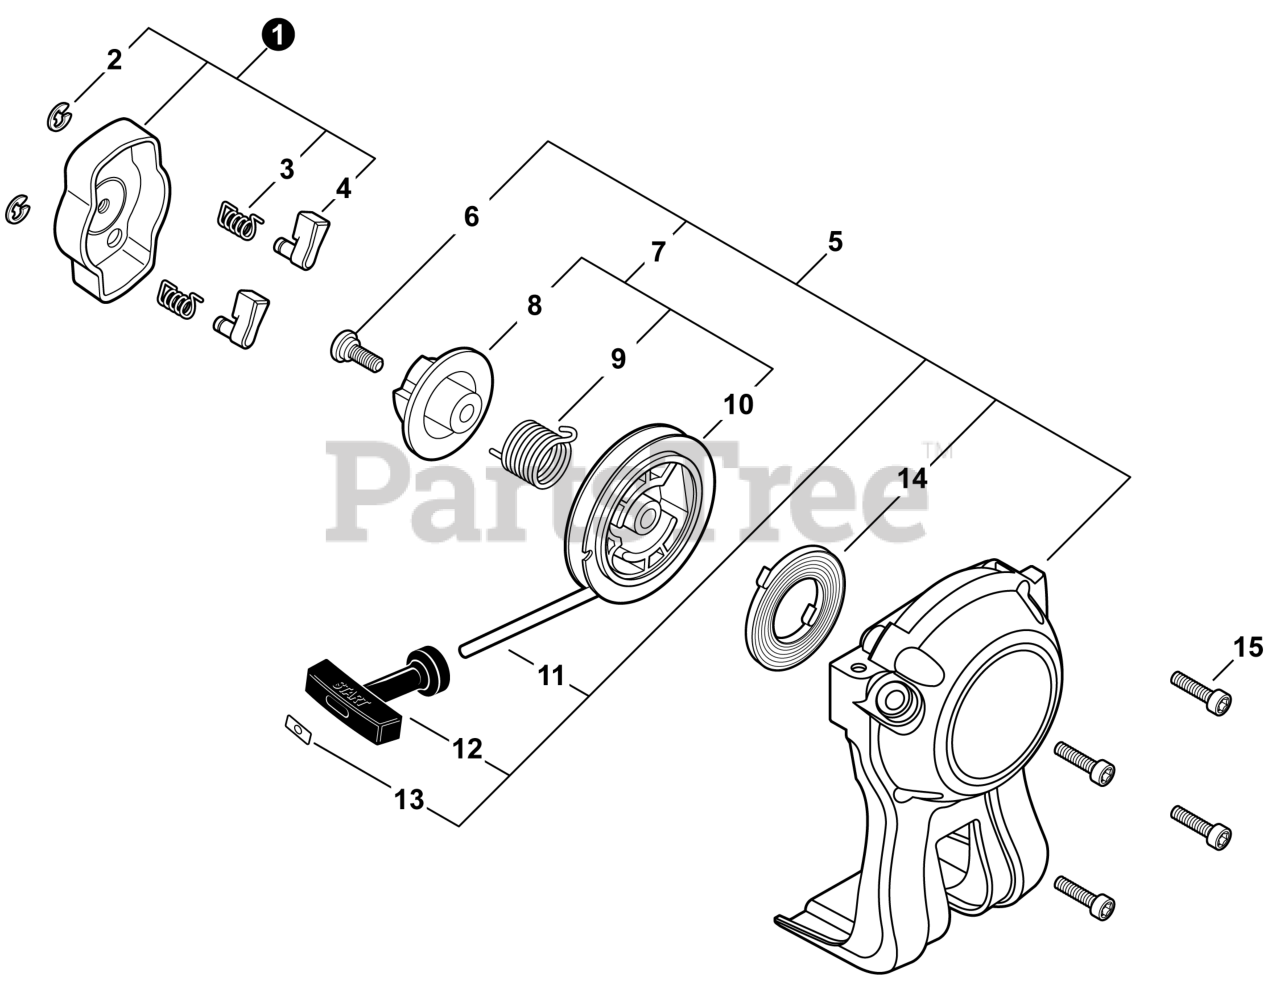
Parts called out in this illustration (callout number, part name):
1	PAWL ASSY, STARTER
2	E-RING 4
3	SPRING, RETURN
4	PAWL, STARTER
5	STARTER ASSY, RECOIL
6	SCREW 5
7	REEL/CAM PLATE SET
8	PLATE, CAM
9	SPRING, TORSION
10	REEL, ROPE
10	ROPE, STARTER 3x700
11	GRIP, STARTER
12	RETAINER, ROPE
13	SPRING, RECOIL
15	BOLT, TORX 4x16
